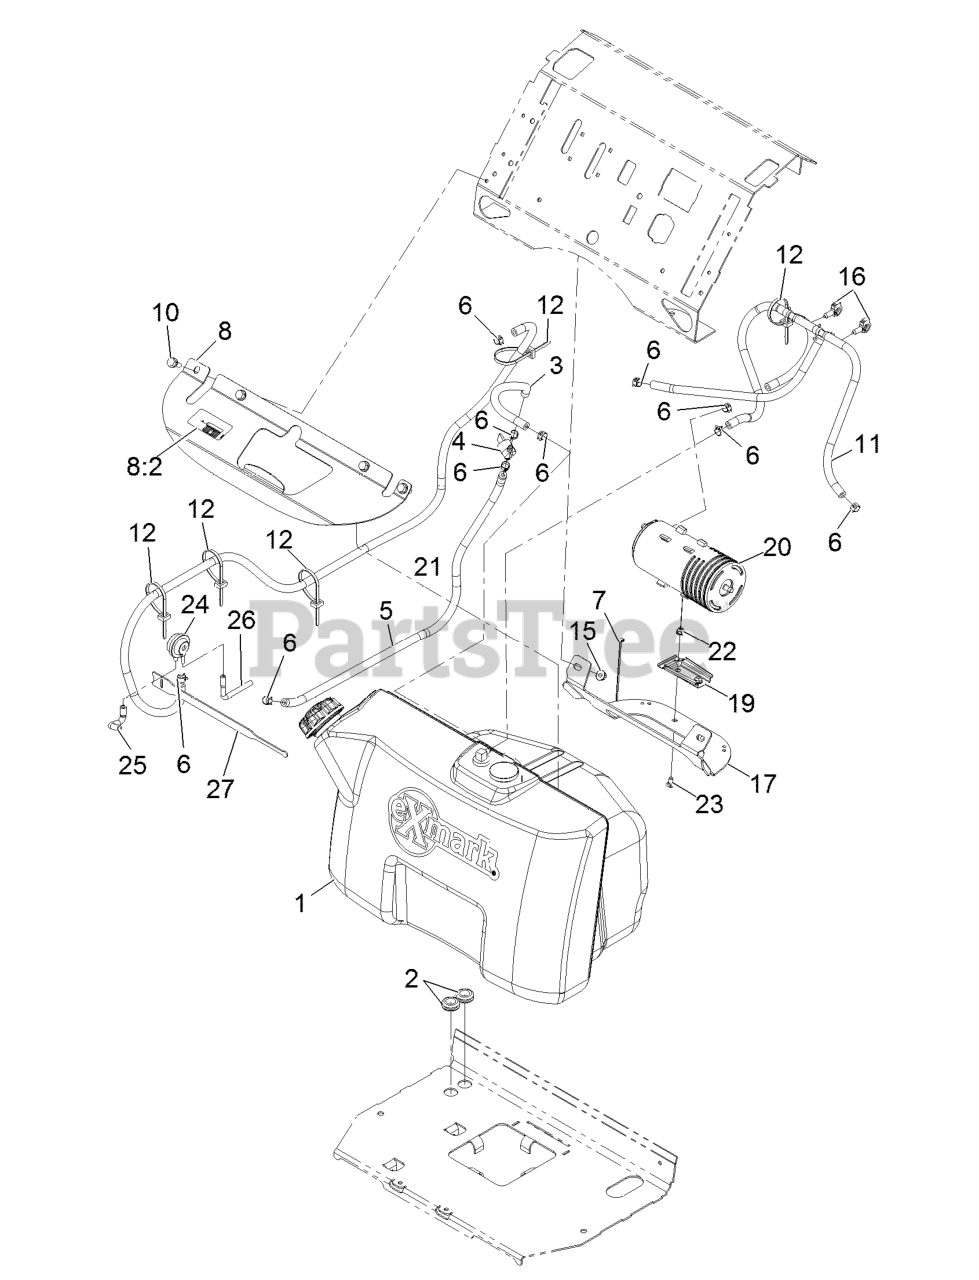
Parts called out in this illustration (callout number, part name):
2	GROMMET
3	HOSE-FUEL
4	VALVE-FUEL
5	HOSE-FUEL
6	CLAMP-HOSE
7	TIE-CABLE
8	BRACKET-TANK
8:2	DECAL-FILL, FUEL
10	Screw-HWH 5/16-18 X 3/4 Tf
11	VENT ASM
12	TIE-CABLE
15	NUT-HF, NI
16	CLIP-HARNESS
17	BRACKET,CARB CANISTER
19	BRACKET-CANISTER, CARBON
20	CANISTER-CARBON, 800CC
21	HOSE-FUEL .25 X 60.00, J3
23	SCREW-CARR
24	VALVE-CONTROL, VACUUM
25	HOSE-VENT, FORMED
26	HOSE-VENT, FORMED
27	STRAP-VELCRO, CABLE TIE
